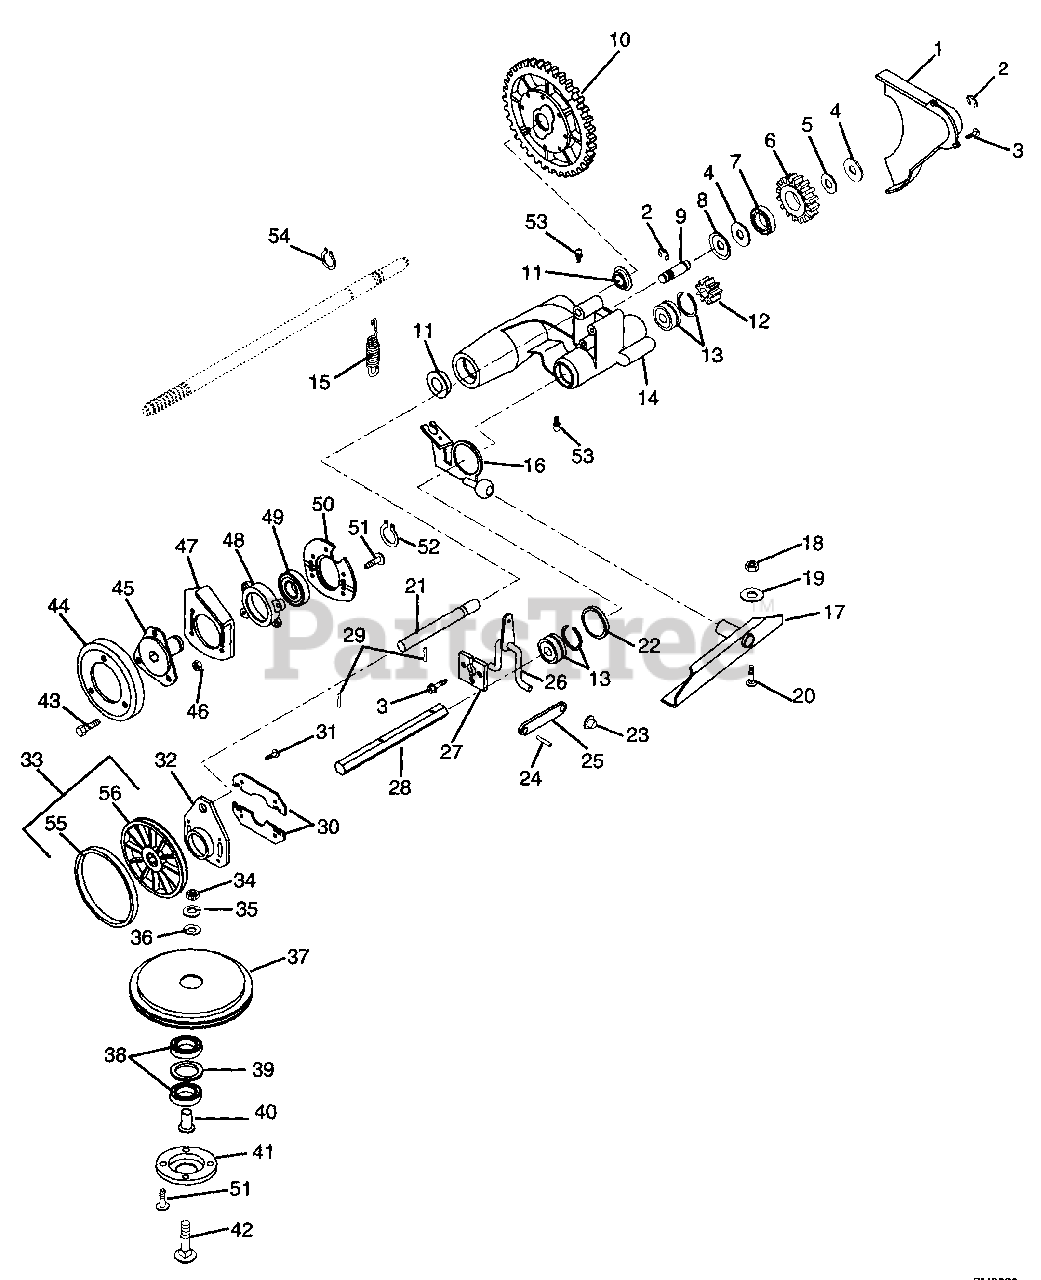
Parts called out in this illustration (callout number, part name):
1	GEAR COVER
2	RG-RTNG-EXT .438X.035
3	SCR-TAP 12-24X.50 HWH PL TR
4	WSHR-FL-STL .520X.827X.062 YZ
5	WSHR-FL-STL .505X.880X.072 PL
6	IDLER GEAR
7	BRG-BALL .500X1.38X.437
8	RETAINER
9	IDLER SHAFT
10	DIFFERENTIAL ASSEMBLY
11	BRG-BALL .625X1.383X.50
13	BRG-BALL .562X1.375X.437
14	DRIVE MOUNT
15	SG-TENS .051X.60X2.25 WLD 7.0
16	DRIVE ACTUATOR WELDMENT
17	PIVOT CHANNEL WELDMENT
18	NUT-LK .312-18 GR A PL
19	WSHR-FL-STL.344X.688X.065PL
20	BLT-RDHDSQNK .312-18X.62SHTPL
21	ROD - GUIDE
22	WSHR-FL-STL 1.390X2.00X.020 PL
23	PUSH NUT, .25
24	PIN-ROLL .125X.50
24	PIN-ROLL .125X.63
25	SHIFT LINK
26	SHIFT ARM WELDMENT
27	RETAINER PLATE
28	HEX SHAFT
29	PIN-ROLL .188X.88
30	THRUST PLATE
31	SCR-TAP 10-24X.375 HWH PL TR
32	GUIDE PLATE
33	FRICTION WHEEL ASSEMBLY
34	NUT-HEX .312-18
35	WSHR-LK .312X.097 PL HVY
36	WSHR-FL-STL .328X.875X.062 PL
37	FRICTION SHEAVE
38	BRG-BALL .625X1.375X.44
39	WSHR-FL-STL 1.062X1.344X.032PL
40	SPINDLE - BEARING
41	RETAINER - BEARING
42	BLT-RDHDSQNK .31-18X1.75 PL
43	BLT-HEX .25-20X.50 PL GR5
44	FRICTION DISC
45	FRICTION WHEEL HUB
46	NUT-LK-CTR .250-20 PL
47	BEARING PLATE
48	BEARING RETAINER
49	BRG-BALL 1.0X2.0X.56
50	BEARING RETAINER
51	TAPTITE M5-0.8X16MM H-FL-PL
52	RG-RTNG-EXT 1.00X.042
53	FTG-LUBE .25-28X.256 YWZC
54	RG-RTNG-EXT .625X.035
55	FRICTION RING
56	FRICTION WHEEL HUB
